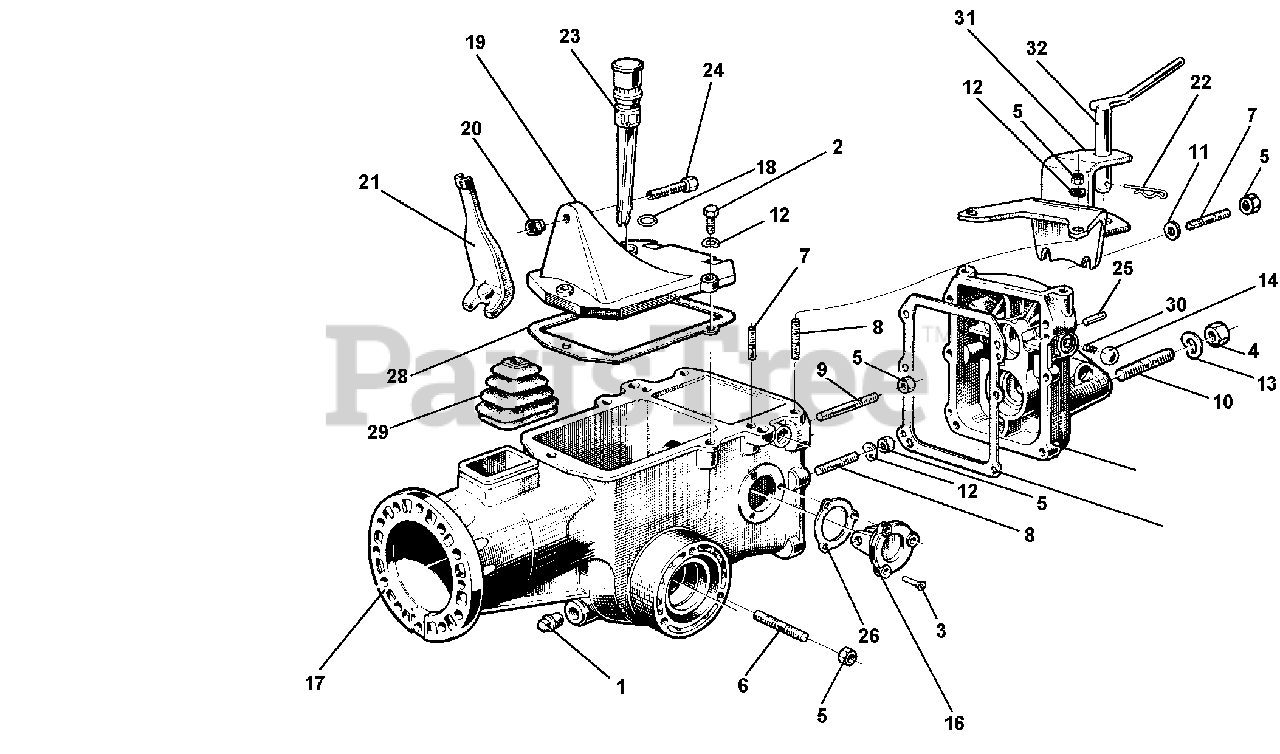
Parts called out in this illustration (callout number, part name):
1	PLUG 1/4 GAS
2	SCREW TE M8 X 25
3	SCREW TSV M6 X 16 UNI 260-5S
4	NUT M12 X 1.25 UNI 5587 6S
5	NUT, SELF LOCKING M8
6	STUD M8 X 46 X 20 X 12
7	STUD M8 X 38 X 14 X 20
8	STUD M8 X 46 X 16 X 16
9	STUD M8 X 58 X 16 X 16
10	ST.56XM12X1.25X26XM12X22 8G
11	WASHER, FLAT 8.4
12	WASHER, LOCK 8.4
13	WASEHR, LOCK 13
14	BALL 15/32 RIV RB-11.906
15	HOUSING COVER
16	FLANGE, REVERSE SPEED
17	CASING 5 SPEEDS GEARBOX
18	RUBBER RING
20	STOP RING NUT
21	CLUTCH LEVER
23	CAP, WITH MEASURING ROD
24	SCREW, ADJUSTING M8
25	PARALLEL PIN D 6 X 20
27	GASKET, COVER
28	GASKET, COVER
31	TOW COUPLING
